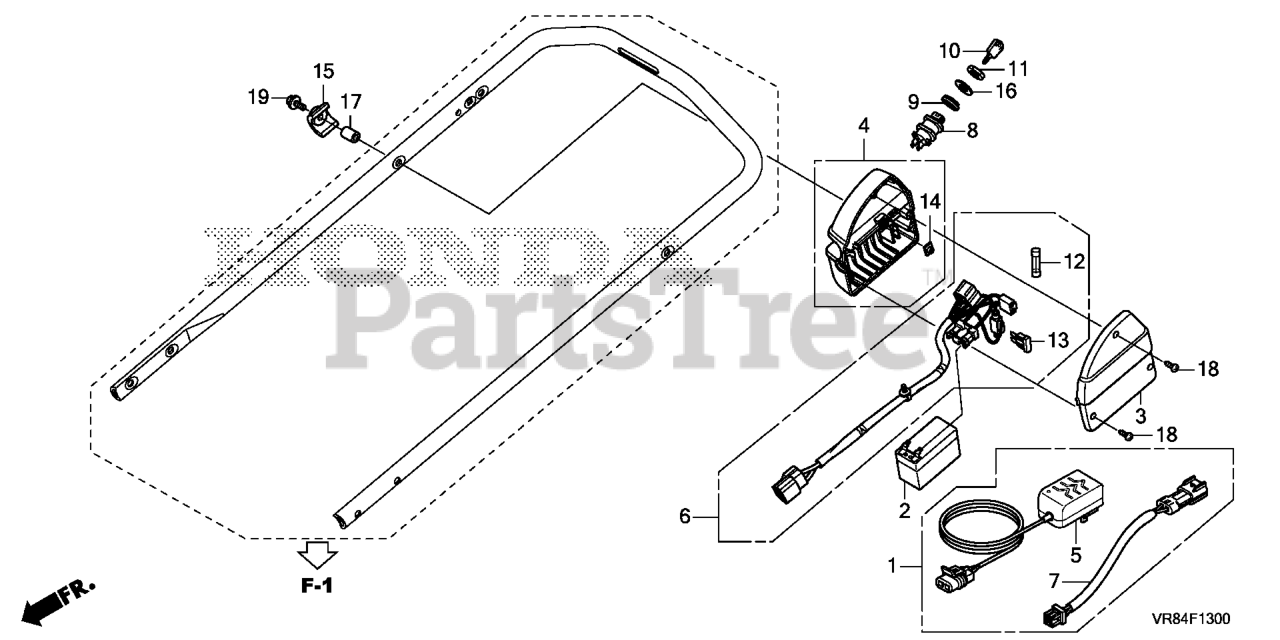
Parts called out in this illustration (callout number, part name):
1	CHARGER KIT, HARNESS
1	CHARGER ASSY., BATTERY (FLOAT-CHG)
2	BATTERY ASSY. (MSDS)
3	COVER, BATTERY
4	BOX, BATTERY
5	CHARGER ASSY., BATTERY (FLOAT-CHG)
6	HARNESS ASSY., MAIN
7	HARNESS ASSY., CHARGER
8	SWITCH ASSY., MOMENT
9	BASE, MOMENT SWITCH
11	NUT, SWITCH
12	FUSE A (30A) (SLO-BLO)
13	FUSE, BLADE (3A)
14	NUT, SPECIAL (6X7)
15	WASHER, FRAME JOINT
16	WASHER, SWITCH
17	COLLAR, BATTERY MOUNTING
18	SCREW, TAPPING (4X16)
19	BOLT, FLANGE (6X35)
